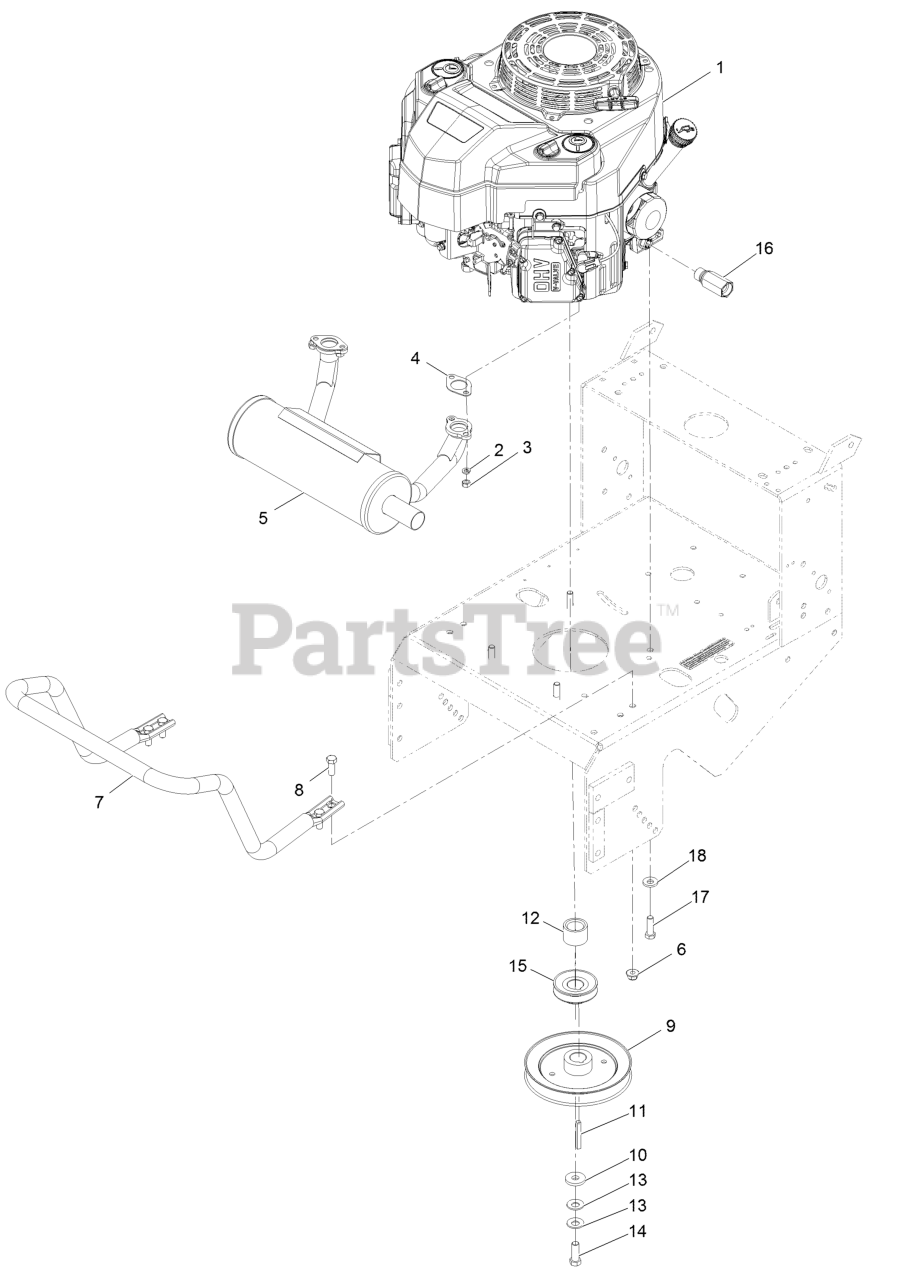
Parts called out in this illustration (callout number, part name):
1	Engine-Kawasaki
2	Washer-Spring Lock M8
4	Gasket-Exhaust
5	Muffler-Horizontal, Offset
6	Nut-Nyloc 3/8-16 Flg
7	Guard-Muffler
8	Screw-HH 3/8-16 X 1
9	Sheave
12	Spacer-Clutch
13	Washer-Spring Disc 7/16
14	Screw-HH
15	Sheave-Transmission
16	Adapter
17	Screw-HH 3/8-16 X 1 1/4
18	Washer-Spring Disc 3/8
